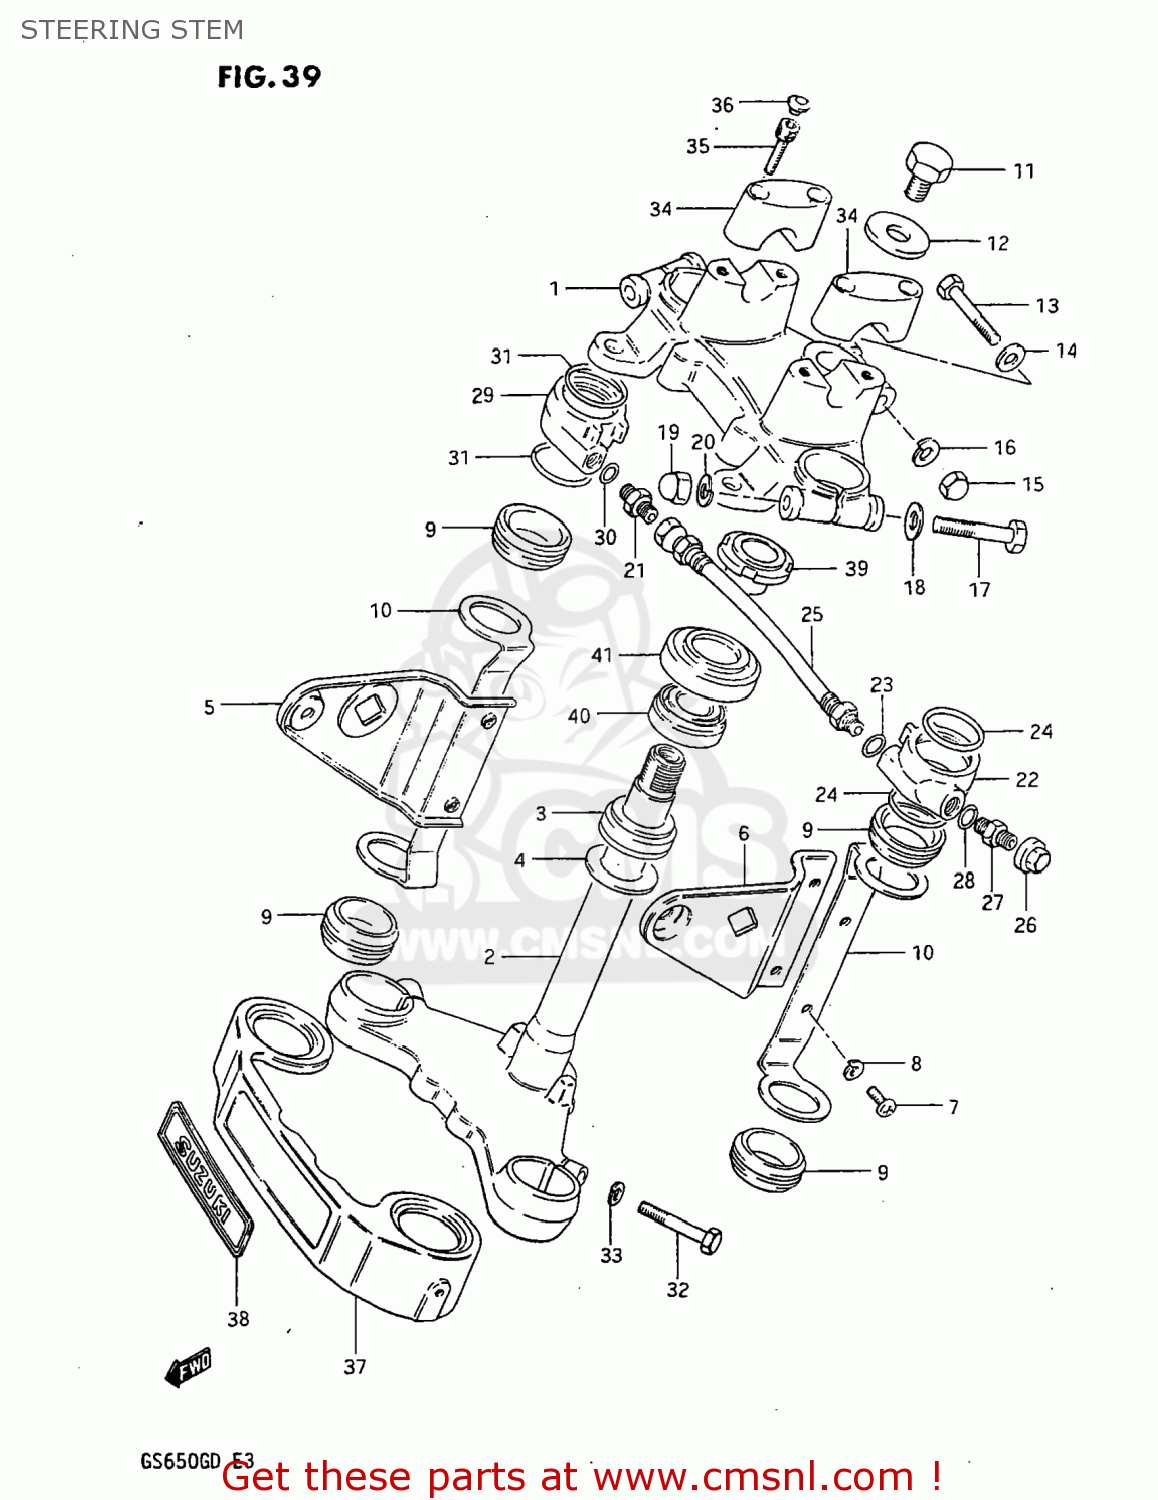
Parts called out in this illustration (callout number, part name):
1	HEAD,STEERING STEM
2	STEM,STEERING
3	BEARING
4	WASHER,THRUST
5	BRACKET,HEADLAMP,RIGHT
6	BRACKET,HEADLAMP,LEFT
7	SCREW
8	LOCK WASHER
9	CUSHION,HEADLAMP HSG BRACKET
10	FRAME,HEAD LAMP BRACKET
11	BOLT,STEERING STEM HEAD
12	WASHER
13	BOLT 8X50
14	WASHER
15	NUT,M8X1.25X12
16	LOCK WASHER
17	BOLT 10X55
18	WASHER
19	NUT
20	LOCK WASHER
21	CONNECTOR
22	JOINT,AIR,LEFT
23	O-RING
24	O RING,B B
25	JOINT,AIR TURBO
26	CAP,FRONT FORK AIR VALVE
27	VALVE,AIR
28	O-RING
29	JOINT,AIR,RIGHT
30	O-RING
31	O RING,B B
32	BOLT 10X40
33	LOCK WASHER
34	HOLDER,HANDLEBAR
35	BOLT
36	CAP(OD:14.5)
37	COVER,FRONT FORK
38	EMBLEM
39	NUT,STEERING STEM
40	TAPER,ROLLER BEARING
41	DUST SEAL,STEERING UPR
